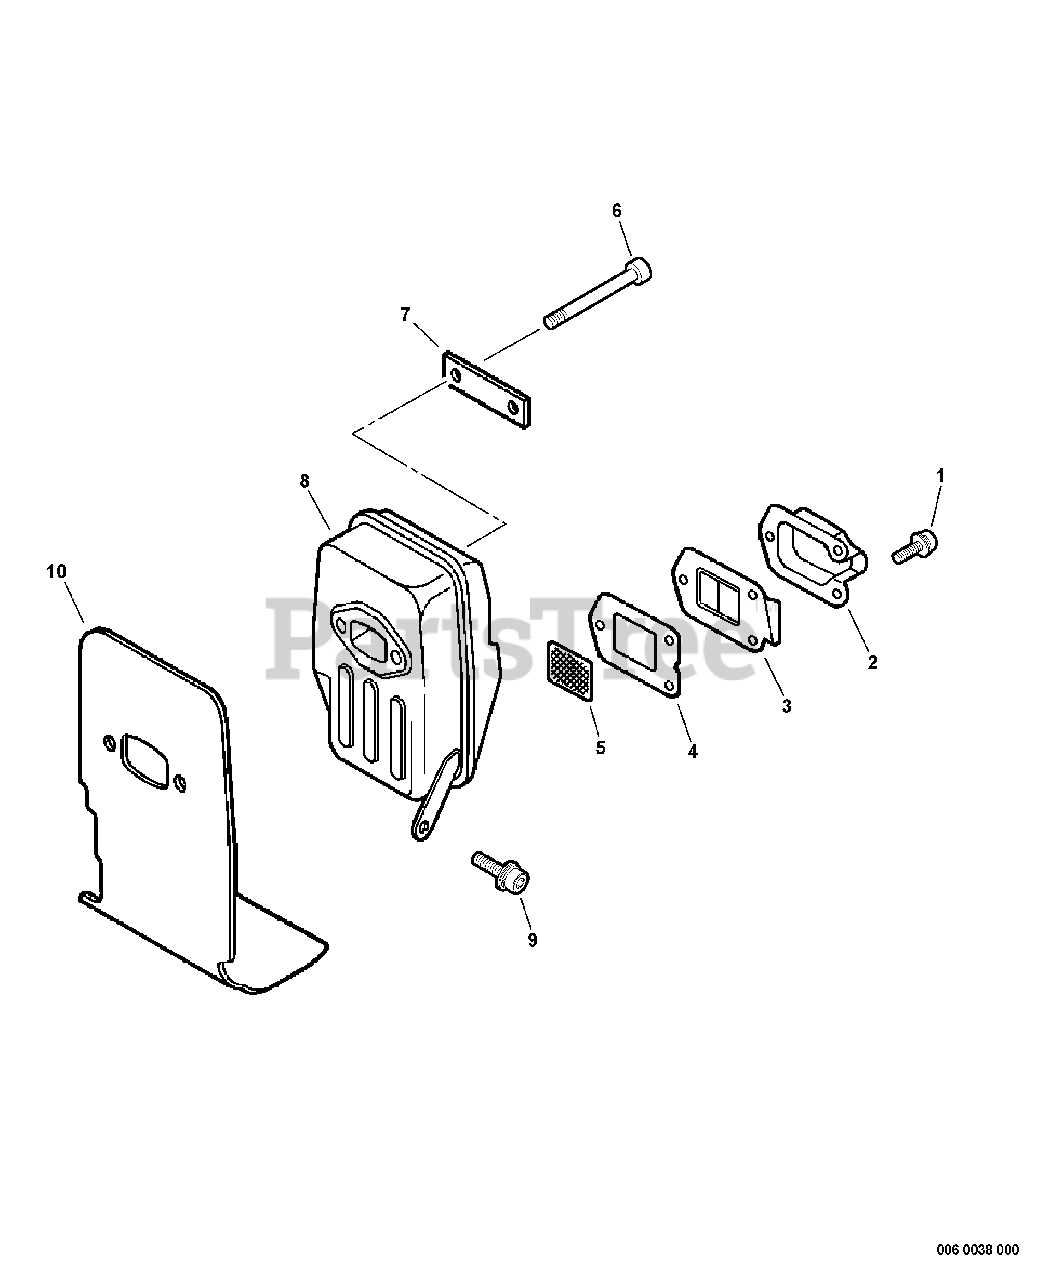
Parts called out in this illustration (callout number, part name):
1	SCREW 4×10
2	OUTLET, EXHAUST
3	GUIDE, EXHAUST
4	GASKET, EXHAUST
5	SCREEN, SPARK ARRESTER
6	BOLT 6×60
7	PLATE, EYE
8	MUFFLER
9	BOLT 5×12
10	HEAT SHIELD, EXHAUST
